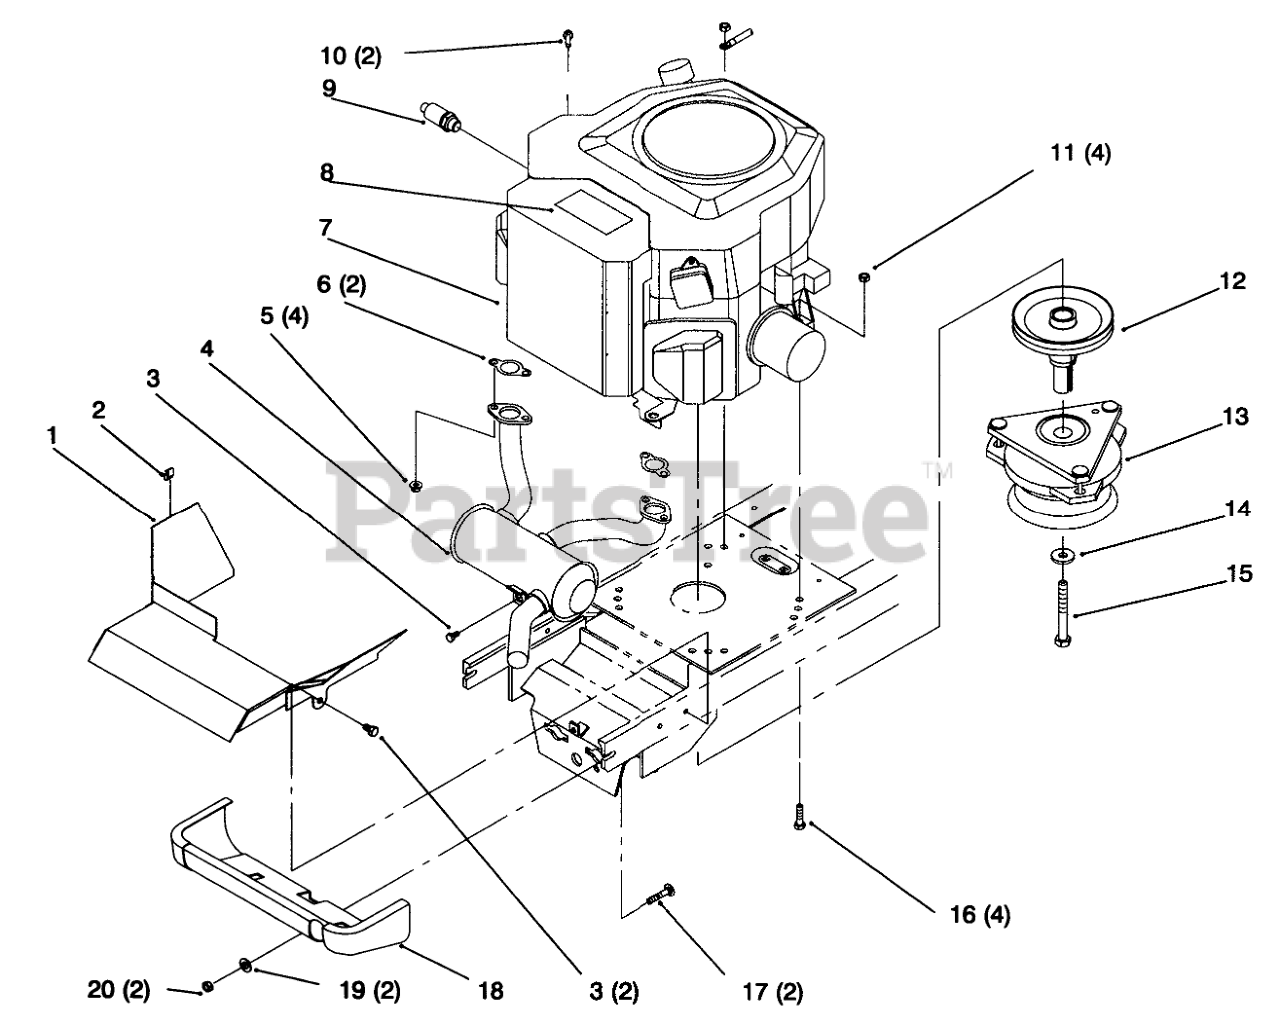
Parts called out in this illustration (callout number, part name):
1	Muffler Baffle ASM
2	CLIP-RETAINER, WIRE
3	SCREW-HWHTF
4	Muffler
5	NUT-HF
6	GASKET-EXHAUST
7	Engine-Kohler 17 (Only On: 72085)
7	Engine-Kohler 17 (Only On: 72104)
8	Decal-Toro Power Plus 17
9	VALVE-DRAIN, OIL
10	SCREW-PPH
11	NUT-LOCK, NI
12	PULLEY-ENGINE
13	Clutch-PTO (Only On: 72104)
13	Clutch-Electric PTO (Only On: 72085)
14	WASHER
15	SCREW-HH
16	SCREW-HH
17	BOLT-CARR
18	Shield-Muffler
19	WASHER-FLAT
20	NUT-LOCK, NI
